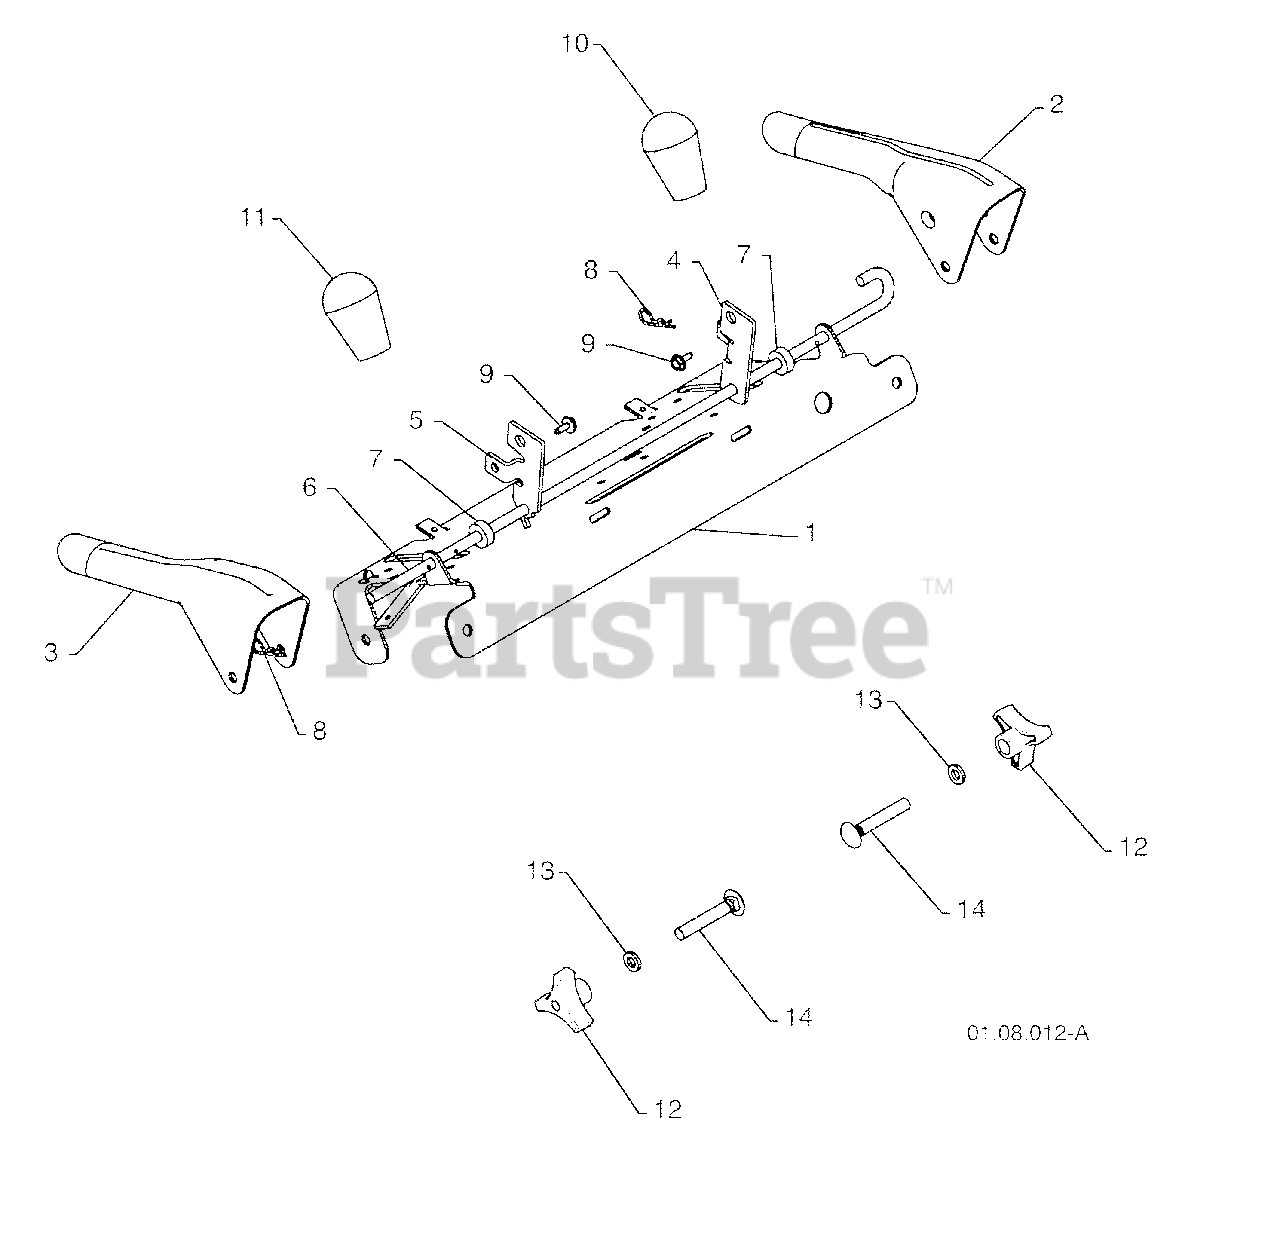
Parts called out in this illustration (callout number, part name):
1	CONTROL PANEL
2	CONTROL LEVER LH
3	CONTROL LEVER RH
4	TRACTION ROD ARM
5	IMPELLER ROD ARM
6	INTERLOCK ROD
9	SCREW 1/4-20 X .50
10	KNOB BLACK
12	HANDLE KNOB
13	WASHER 3/8
14	CARRIAGE BOLT 3/8-16 X 2.25
